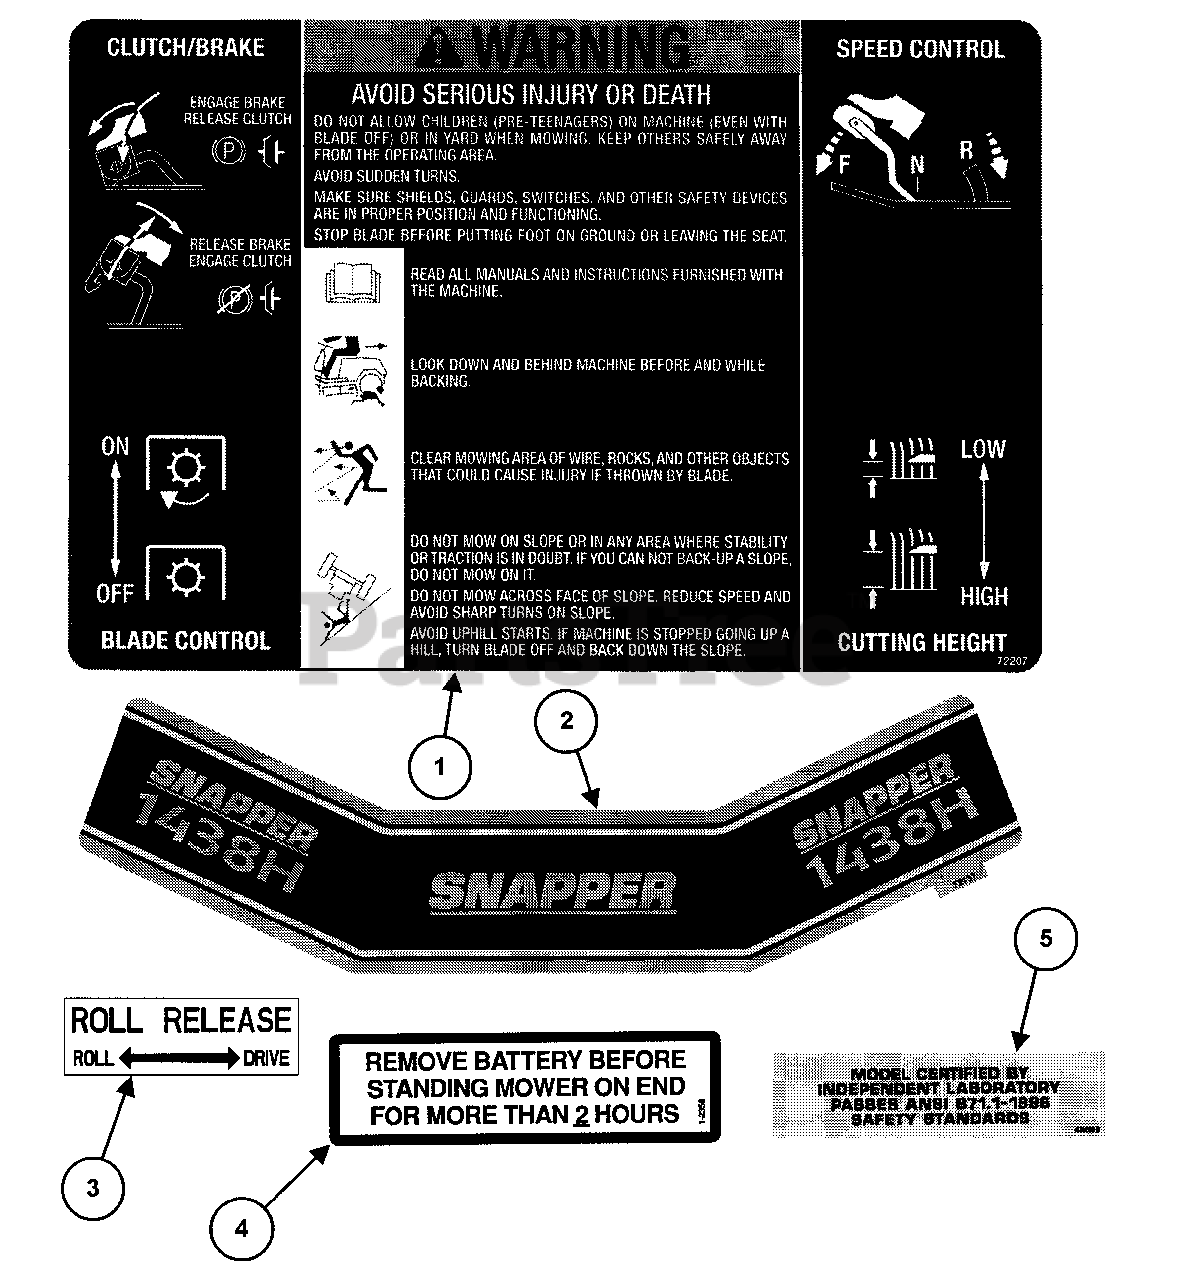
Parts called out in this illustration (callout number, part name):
1	DECAL, Control/Warning
2	DECAL, Steering Column
3	DECAL, Roll Release
4	DECAL, Battery
5	DECAL, Certification
